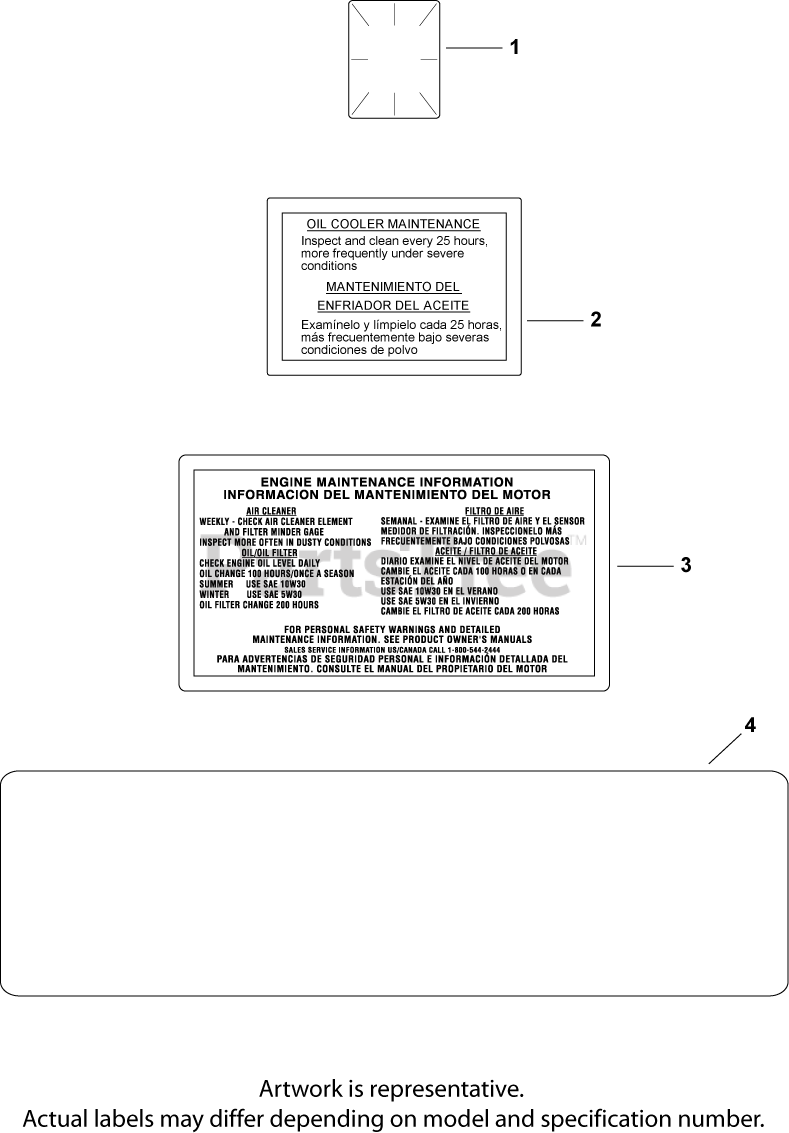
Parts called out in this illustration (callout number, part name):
1	DECAL, CLEAR LAMINATE USE 25 113 70-S
2	DECAL, OIL COOLER MAINTENANCE-DISC.
3	DECAL, ENGINE MAINTENANCE - DISC.
4	DECAL, 30 HP - DISCONTINUED
